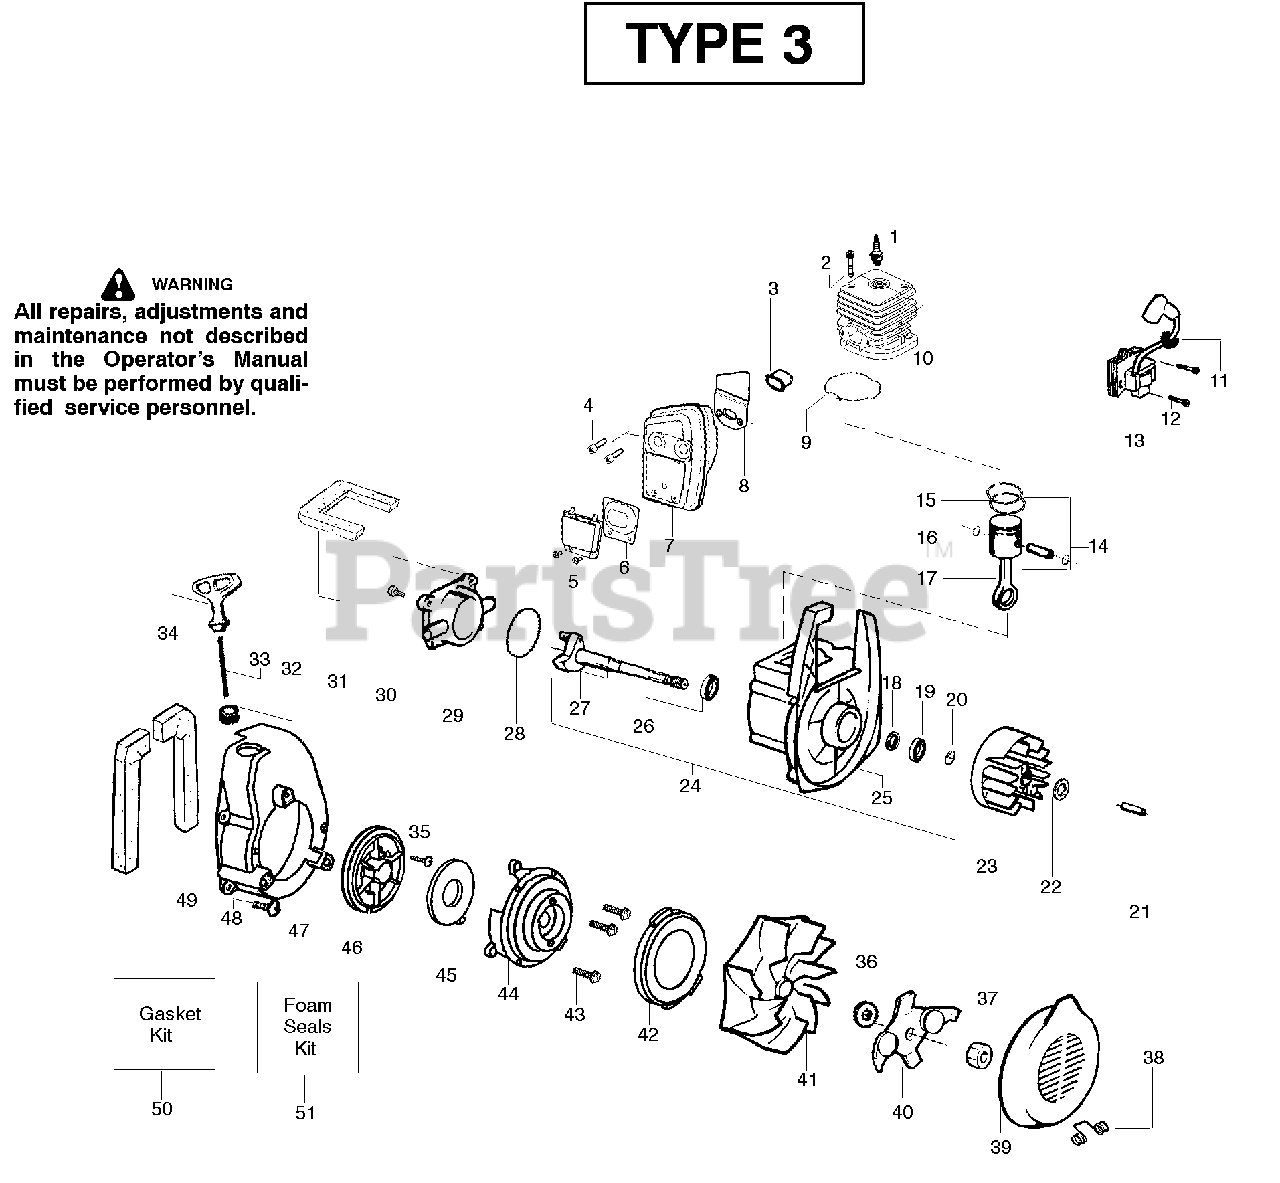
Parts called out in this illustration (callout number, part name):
1	Spark Plug (RCJ-6Y)
3	Insulator-Heat
4	Screw-Muffler-Internal
5	Screw
6	Kit-Spark Screen
7	Kit-Muffler
8	Gasket-Baffle (kit)
9	Gasket-Cylinder (kit)
10	Kit-Cylinder
11	Grommet-Ign. Module
12	Screw-Ignition Module
13	Ignition Module
14	Kit-Piston
15	Piston Ring
16	Retainer-Piston Pin
17	Assy-Connecting Rod
18	Seal-Crankcase
19	Bearing-Outer
20	Retainer Ring-C'chaft
21	Spacer-Flywheel
23	Assy-Flywheel
24	Assy-Crankcase/Crank shaft
25	Assy-Crankcase
26	Bearing-Inner
27	Assy-Crankshaft
28	O-ring-C/case (kit)
29	Cover-Crankcase
30	Screw
31	Foam-219mm (kit)
32	Eyelet-Flange
33	Kit-Rope
34	Handle-Starter
35	Screw-Rope
36	Washer-Belleville
38	Spring-Return Cover
39	Inlet Door
40	Assy-Mulch Blade
41	Assy-Impeller
42	Seal-Ring
44	Housing-Pulley
45	Spring-Starter
46	Kit-Starter Pulley
47	Fan Housing
48	Screw
49	Foam-182mm (kit)
50	Kit-Gasket
51	Kit-Foam Seals
